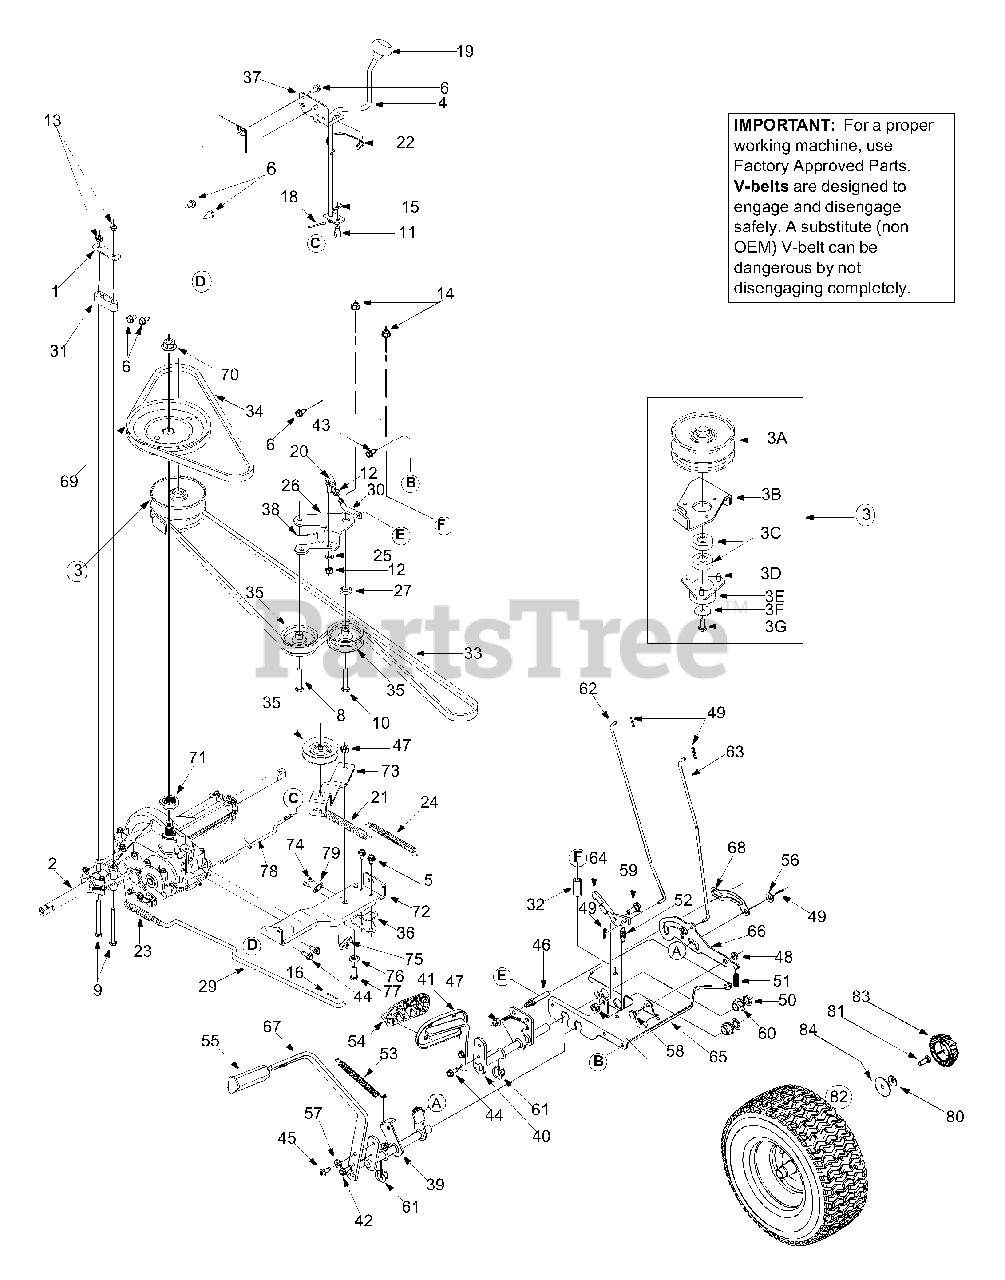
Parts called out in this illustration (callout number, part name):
2	Drive Assembly
3	Variable Spd. Pulley Assembly
3A	Var. Spd. Pulley
3B	Bracket: Variable Speed
3C	Ball Bearing
3D	TT Screw 1/4-20 x 0.75
3G	Hex Bolt 5/16-24 x 0.75
4	Shift Lever Assembly
5	TT Screw 5/16-18 x 0.5
6	AB Screw 5/16-12 x 0.75
7	TT Screw 1/4-20 x 1.25
8	TT Sems Screw 3/8-16 x 1.5
9	Hex Bolt 5/16-18 x 3.5
10	Hex Bolt 3/8-16 x 2.0
12	Hex Nut 3/8-24
13	Hex Lock Nut 5/16-18
14	Flange Lock Nut 3/8-16
15	Hairpin Clip
17	Hairpin Clip
20	Ball Joint
21	Extension Spring
23	Extension Spring
24	Extension Spring
25	Lock Washer 3/8
26	Grease
27	Shoulder Spacer
28	Shift Rod
30	Idler Adj. Rod
31	Spacer: Transaxle
33	V Belt
34	V Belt
35	Flat Idler Pulley
36	Shift Bracket
37	Shift Bracket
39	Brake Control Assembly
42	TT Screw 5/16-18 x 0.875
43	AB Screw 5/16-12 x 0.75
44	LD Screw 5/16-18 x 0.75
45	TT Screw 5/16-18 x 0.75
46	Pin
47	Hex Lock Nut 3/8-16
48	Flange Lock Nut
50	Push Nut
51	Compression Spring
52	Extension Spring
53	Extension Spring
55	Brake Pad
57	Flat Washer
58	Shoulder Screw
59	Shoulder Screw
60	Hex Flange Bearing
61	Hex Flange Bearing: Split
62	Brake Lock Rod
63	Cruise Control Rod
64	Cruise Latch
66	Lock-Out Bracket
69	Transmission Pulley
70	Flange Nut 9/16-18
71	Pulley Hub
72	Transmission Torque Bracket
73	Idler Bracket
74	AB Screw #8-18 x 0.5
75	Spring Switch
76	Shoulder Spacer
77	Hex Bolt 3/8-16 x 1.0
78	Shift Rod
79	Insulator Nut Plate
81	Hex Cap Screw
83	Hub Cap
